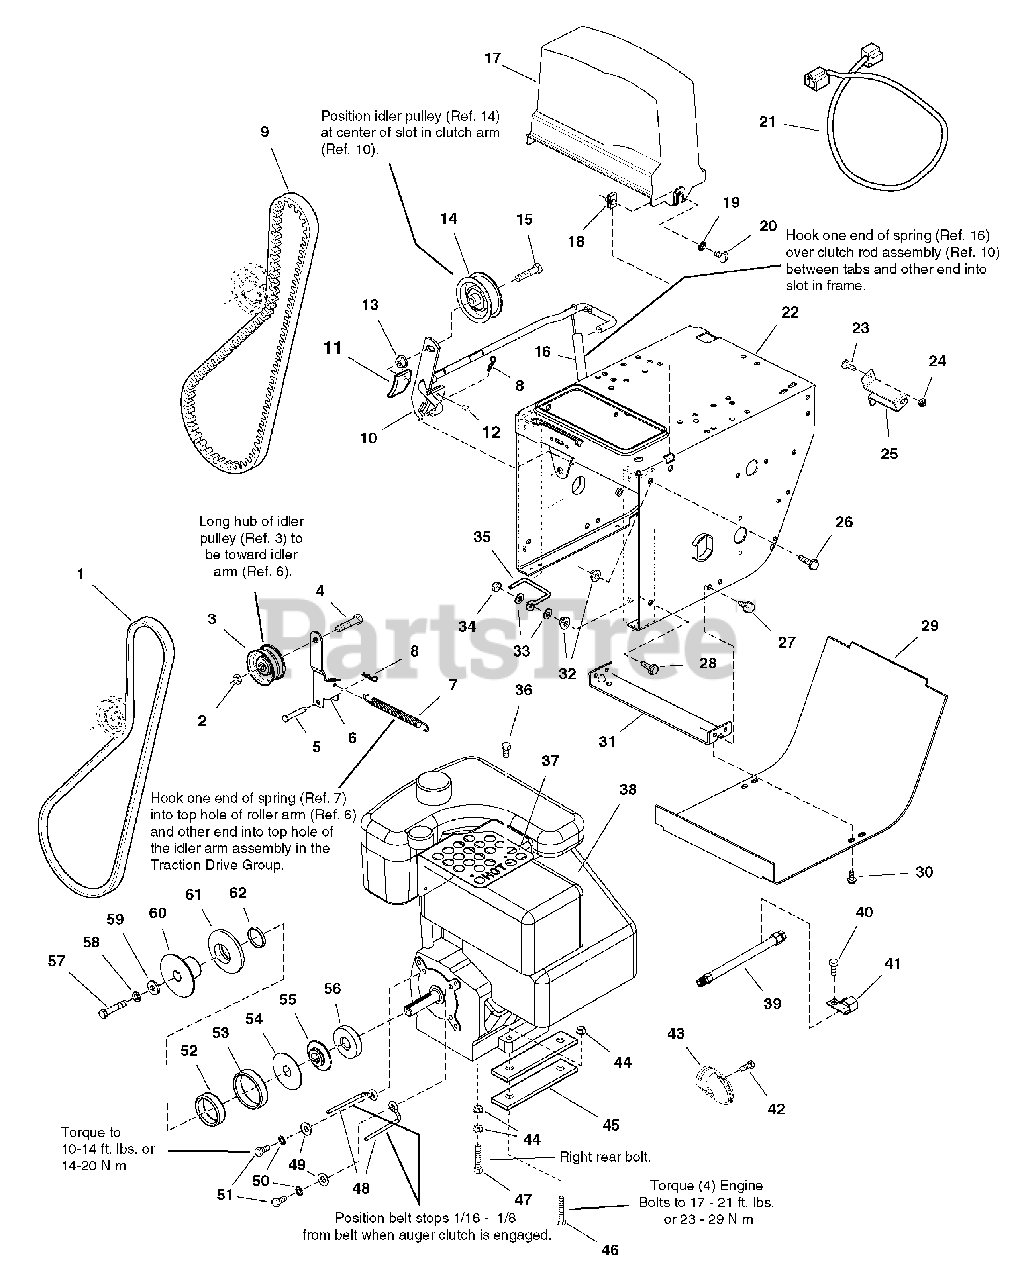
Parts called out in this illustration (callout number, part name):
1	V-BELT, 3L (Used on all models Except 1390 Models)
1	V-BELT, 3L (Used Only on 1390 Models)
2	NUT, Hex, Toplock, Jam, 3/8-16
3	PULLEY, Idler
4	SCREW, Hex Head, 3/8-16 x 1-1/2
5	PIN, Flat Head Drilled
6	ARM, Idler, 5-3/4 LG
7	SPRING, Extension
8	PIN, Quick
9	V-BELT, HA (Used on all models Except 1390 Models)
9	V-BELT, HA (Used Only on 1390 Models)
10	ROD AND ARM ASSEMBLY, Clutch, Brake w/Pad
13	NUT, Hex Flange, 3/8-16 Whiz Lock Large
14	PULLEY, Idler
15	SCREW, Hex Whiz Lock Flange, 3/8-16 x 1-3/4
16	SPRING, Extension
17	COVER, Belt
18	NUT, Speed, 5/16-18, Lug Type
19	LOCKWASHER, External Tooth, 5/16
20	SCREW, Truss head Slotted, 5/16-18 x 3/4
21	CORD, Electric Extension
22	FRAME ASSEMBLY, Chain/Tube Handles
23	CARRIAGE BOLT, 1/4-20 x 3/4 G5
24	NUT, Hex KEPS, 1/4-20, Conical Washer
25	SUPPORT, Clutch Cable, 16GA
26	SCREW, Hex Whiz Lock Flange, 5/16-18 x 3/4
27	SCREW, Hex Washer Head Taptite, 5/16-18 x 3/4
28	SCREW, Hex Whiz, 31/100-18 x 1-1/4
29	COVER, Bottom Frame, 20GA
30	SCREW, Hex Washer Head Taptite, 1/4-20 x 1/2
31	SUPPORT, Tie Bar
32	NUT, Hex Flange, 5/16-18, Whiz Lock Large
33	WASHER, Flat, 11/32 x 3/4 x 1/16
34	NUT, Hex Centerlock, 5/16-18
36	SCREW, Hex Washer Head Taptite, #10-24 x 1/2
37	GUARD, Muffler, 18GA
38	ENGINE, 9.5HP Briggs & Stratton Electric Start
39	HOSE, Oil Drain, w/Fittings
40	CAPSCREW, Hex Washer Head, 5/16-18 x 3/4
42	SCREW, Muffler Deflector
43	DEFLECTOR, Rain Guard, B&S Snow Muffler
44	NUT, Hex Flange, 5/16-18, Whiz Lock Small
45	SUPPORT, Engine Riser (Used on all models Except 1390 Models)
46	CAPSCREW, Hex Whiz Lock Flange, 5/16-18 x 2-1/4 (Used on all models Except 1390 Models)
46	CAPSCREW, Hex Head, 5/16-18 x 1-1/2 G5 (Used Only on 1390 Models)
47	CAPSCREW, Hex Washer Head Taptite, 5/16-18 x 2-1/2 (Used on all models Except 1390 Models)
47	CAPSCREW, Hex Head 5/16-18 x 1-3/4 G5 (Used Only on 1390 Models)
48	STOP, Belt
49	WASHER, 5/16
50	LOCKWASHER, Spring, 5/16
51	CAPSCREW, Hex Head, 5/16-24 x 3/4 G5
52	SPRING, Compression
53	SPRING, Compression
54	WASHER, Thrust
55	PULLEY HALF, Middle
56	PULLEY HALF, Inside
57	CAPSCREW, Hex Head, 3/8-24 x 1-1/2 G8
58	LOCKWASHER, Spring, 3/8
59	WASHER, 3/8
60	PULLEY HALF, Outside
61	PULLEY HALF, Middle
62	WICK, Felt, Oil
